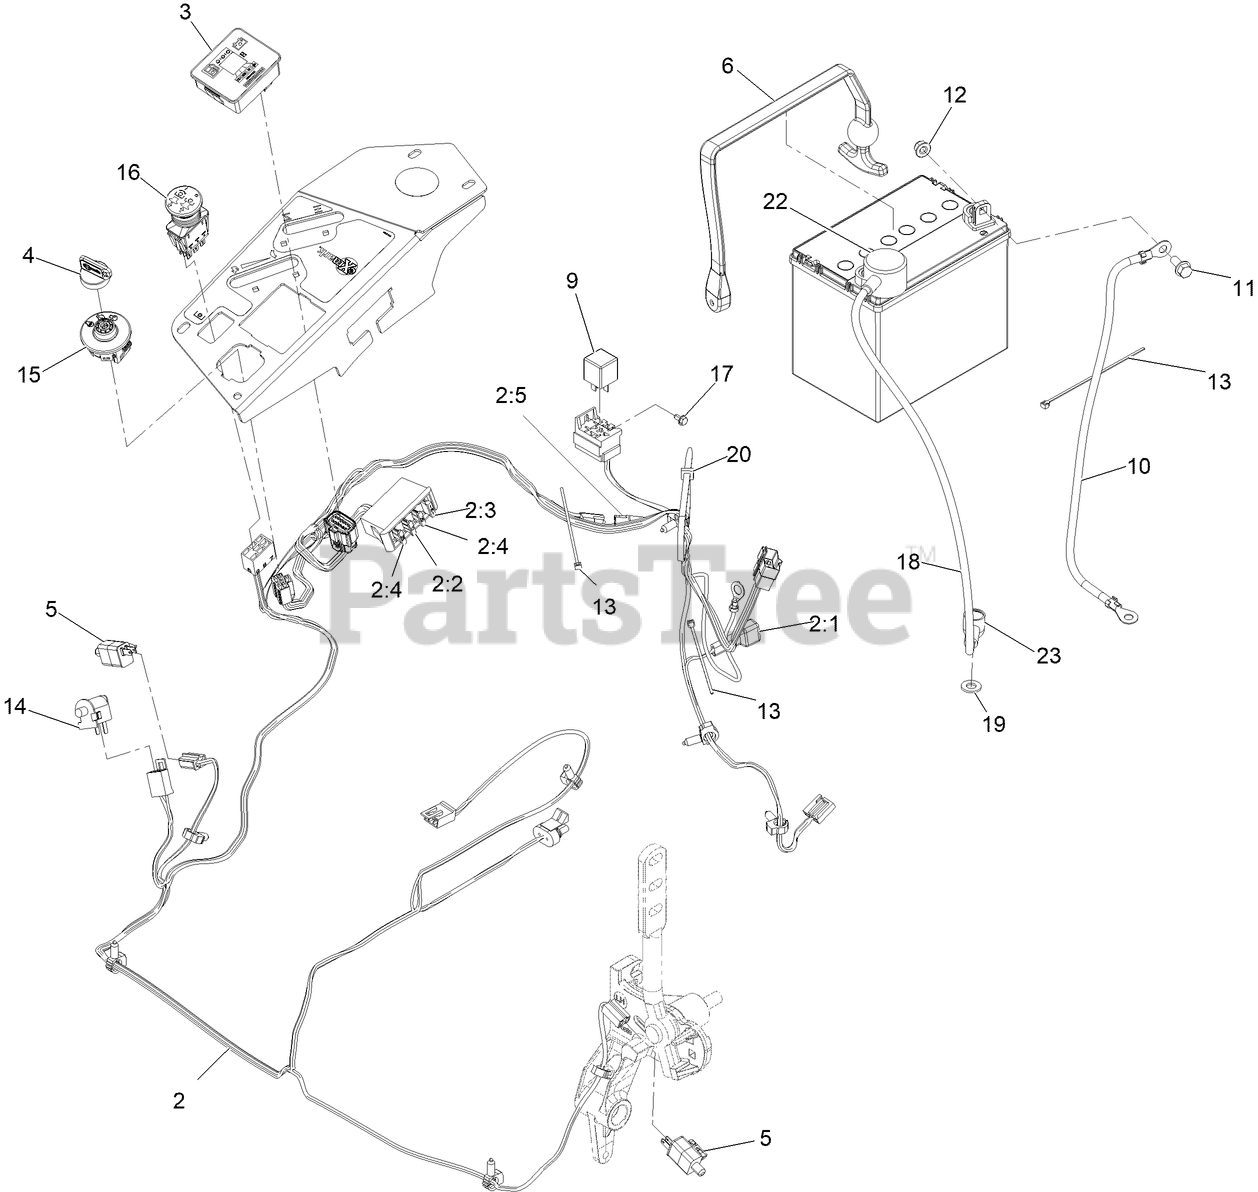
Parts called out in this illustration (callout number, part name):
2	HARNESS-WIRE, MAIN
2:2	FUSE-BLADE, 10 AMP
2:3	FUSE-BLADE, 15 AMP
2:4	FUSE-BLADE, 25 AMP
2:5	CAP-PLUG
3	FUEL/HOUR METER ASM
4	KEYS-IGNITION (SPARE PAIR
4	KEY-IGNITION
6	Strap-Bungee
10	CABLE-BATTERY, NEGATIVE
11	SCREW-HHF
12	NUT-HF, NI
13	TIE-CABLE
14	SWITCH-BAIL
15	SWITCH-IGNITION
16	SWITCH, PTO 10A
17	PLUG-PLASTIC
18	CABLE-BATTERY, POSITIVE
19	WASHER-FLAT
20	TIE-CABLE
22	INSULATOR-BATTERY
23	INSULATOR-SOLENOID
